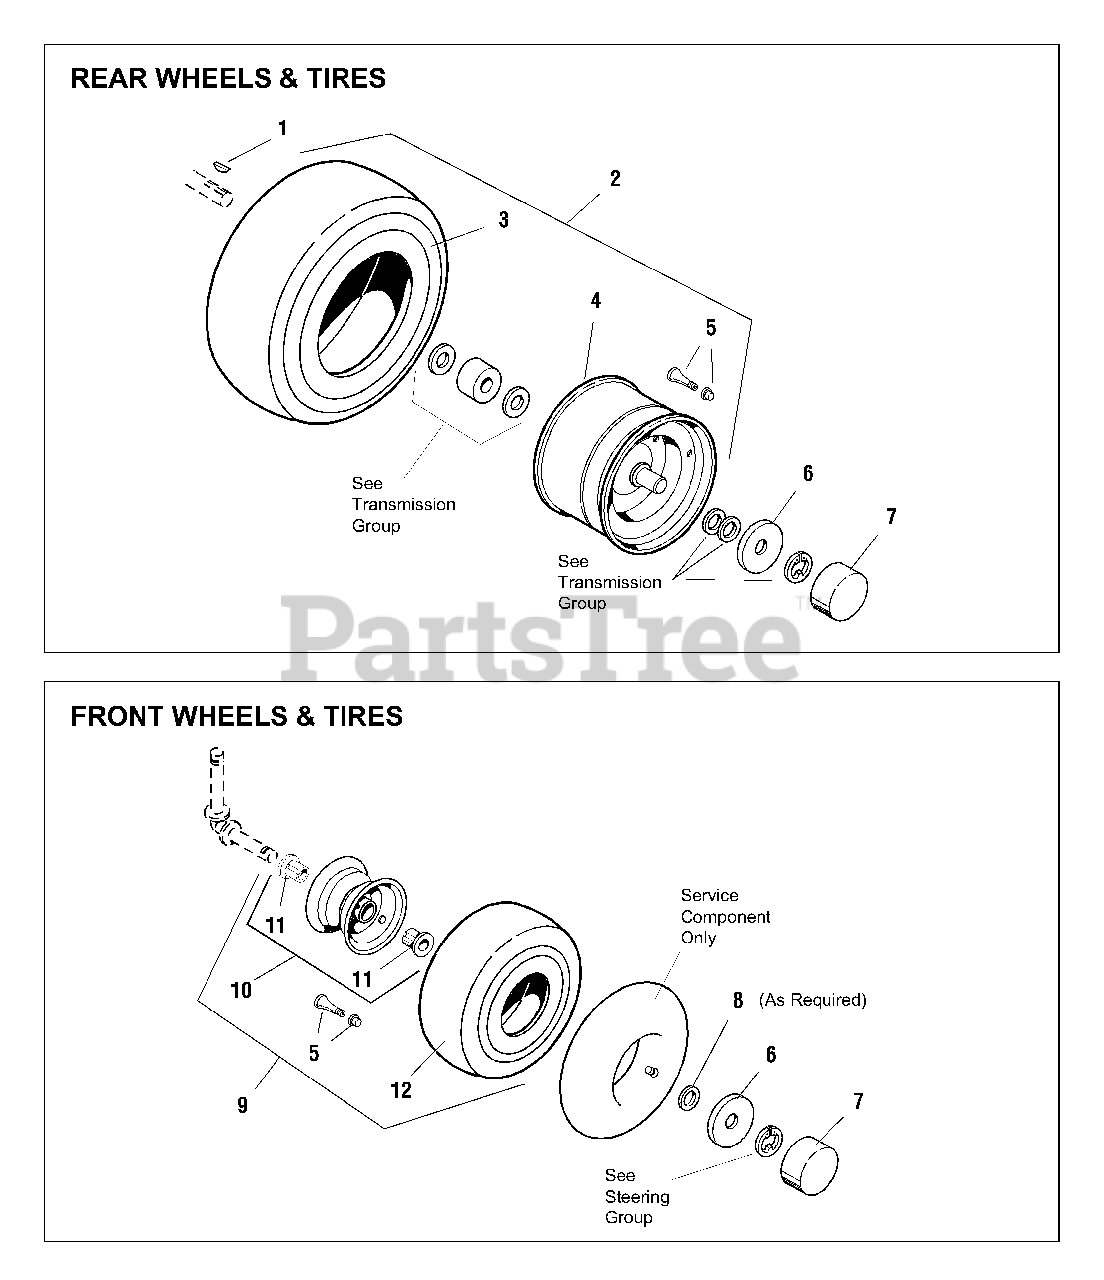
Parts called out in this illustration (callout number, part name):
1	KEY
2	REAR WHEEL & TIRE ASSEMBLY
3	REAR TIRE, 20x8.00-8 2 PLY
3	REAR TIRE, 18x8.50-8 2 PLY
4	REAR WHEEL ASSEMBLY, Rim
5	VALVE STEM & CAP
6	WASHER, 3/4
8	WASHER, 3/4
9	FRONT WHEEL & TIRE ASSEMBLY
10	FRONT WHEEL ASSMBLY, Rim
11	BEARING
12	FRONT TIRE, 15X6.00-6 2 PLY
